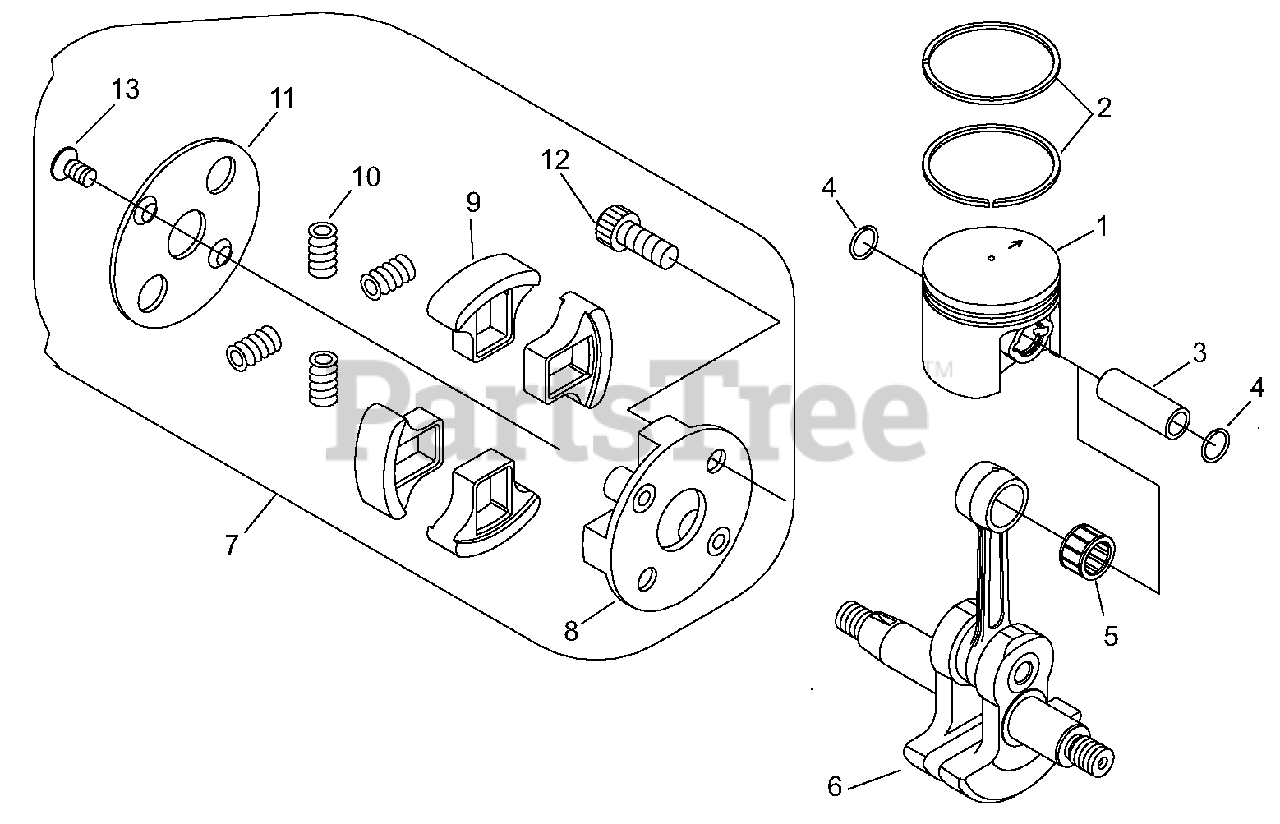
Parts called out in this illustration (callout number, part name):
1	PISTON
2	RING, PISTON
3	PIN, PISTON
4	RING, RETAINING
5	BEARING, NEEDLE
6	CRANKSHAFT ASSY
7	CLUTCH ASSY
8	HUB, CLUTCH
9	SHOE, CLUTCH
10	SPRING, CLUTCH
11	PLATE, CLUTCH
12	BOLT, CLUTCH
13	SCREW
